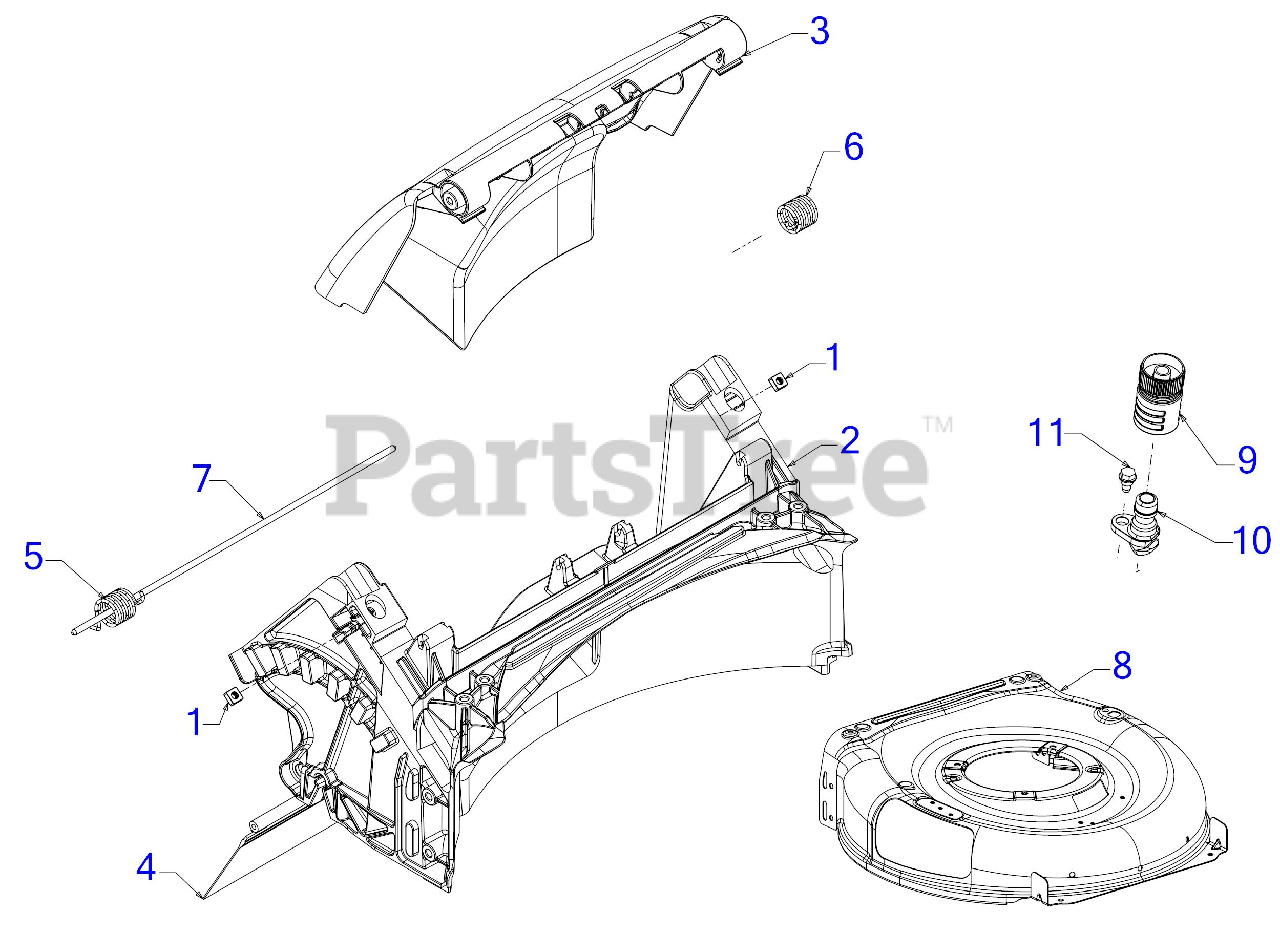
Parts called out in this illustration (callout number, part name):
1	SQUARE NUT 1/4-20
2	REAR BAG DOOR ASSEMBLY
3	REAR BAG DOOR ASSEMBLY
4	TRAILSHIELD
5	TORSION SPRING (RH)
6	TORSION SPRING (LH)
7	REAR DOOR PIVOT ROD
9	WATER NOZZLE
10	DECK WASH NOZZLE
11	SHOULDER SCREW 1/4-20 x .50
